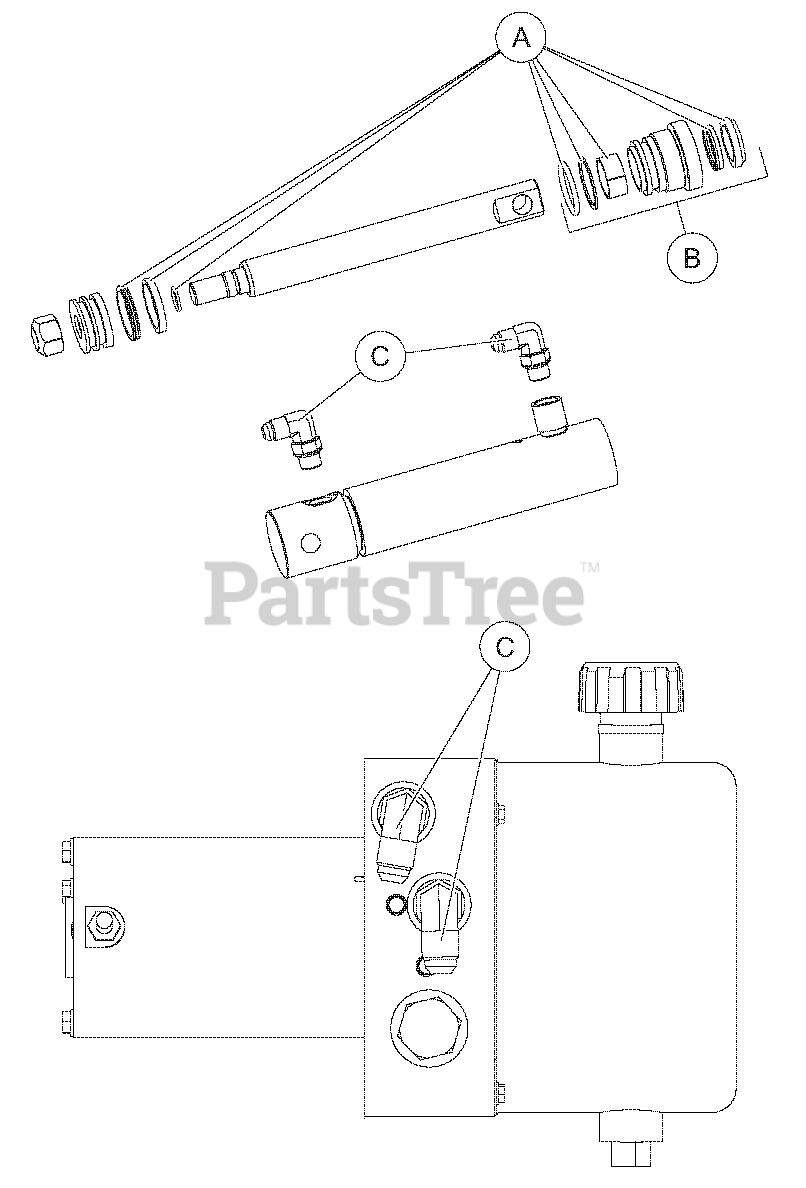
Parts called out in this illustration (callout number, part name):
A	KIT, SEAL RAM 1-1/2 DA
B	ASM, GLAND NUT 1"
C	FTG, 90 MJIC-MORB ELBOW
